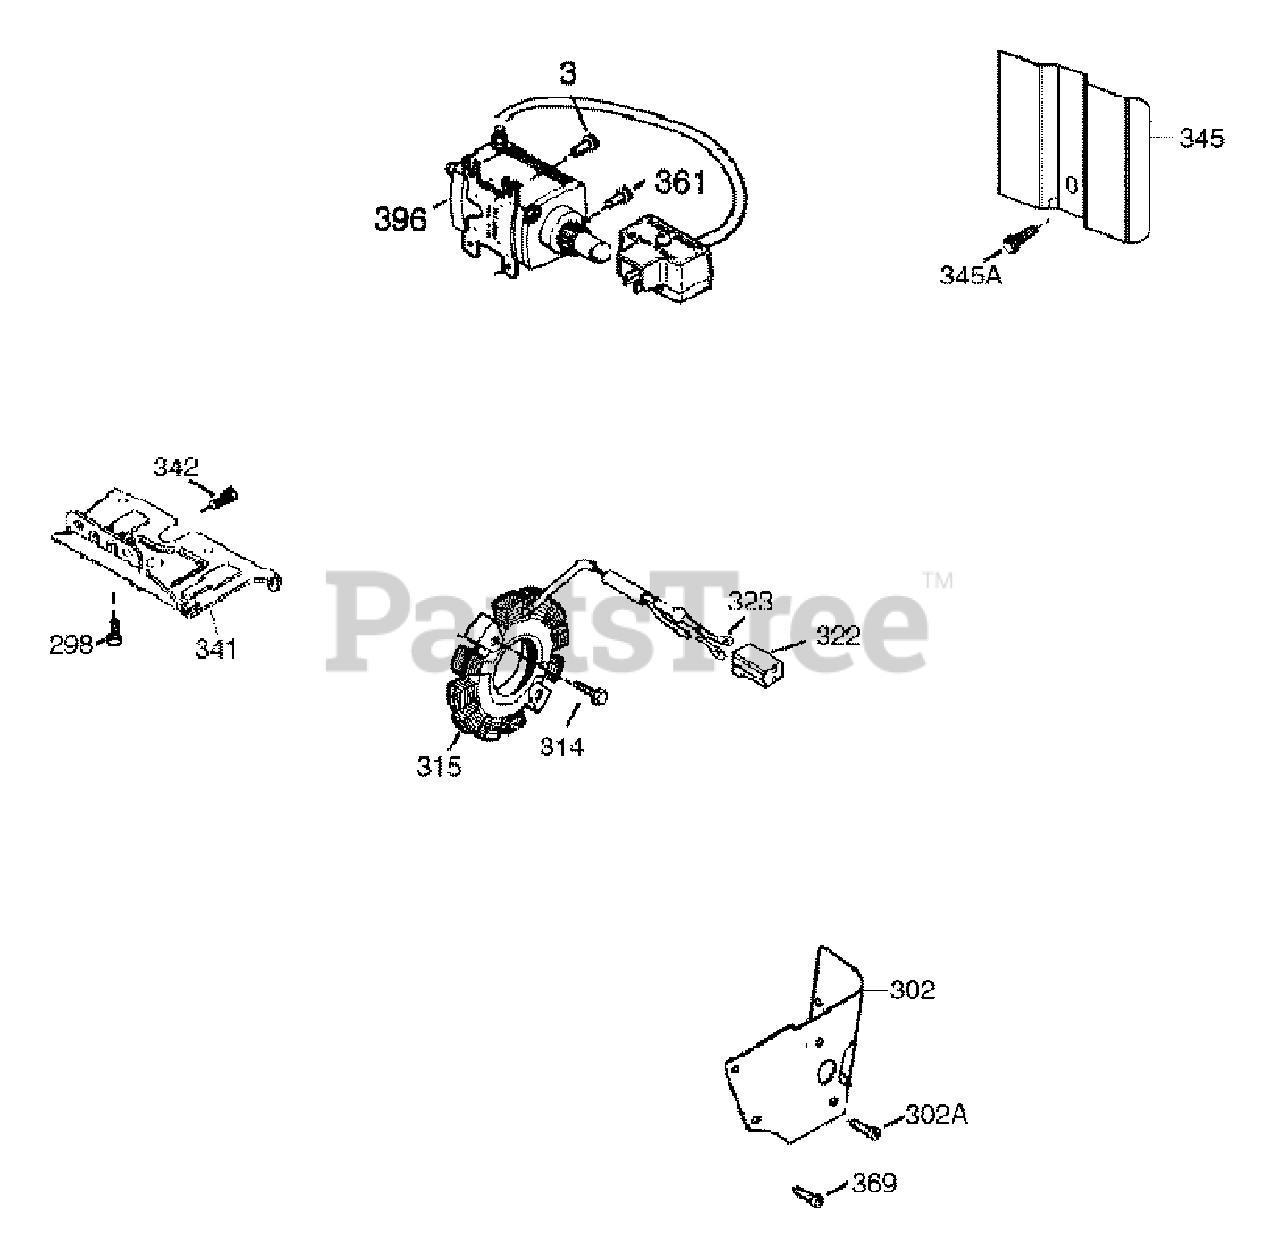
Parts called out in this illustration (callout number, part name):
3	Screw, 1/4-20 x 1/2"
298	Screw, 1/4-15 x 3/4"
301	Fuel Cap
302	Fuel Tank Extension
302A	Screw, 10-32 x 1/2"
314	Screw, 1/4-20 x 3/4"
315	Alternator Coil (18 Watt)
322	Connector Body
341	Fuel Tank Bracket
342	Screw, 5/16-18 x 7/8"
345A	Screw, 10-32 x 1/2"
361	Screw, T-30, 1/4-20 x 15/32"
369	Screw, 12-16 x 5/8"
396	Electric Starter Motor (110 Volt)
